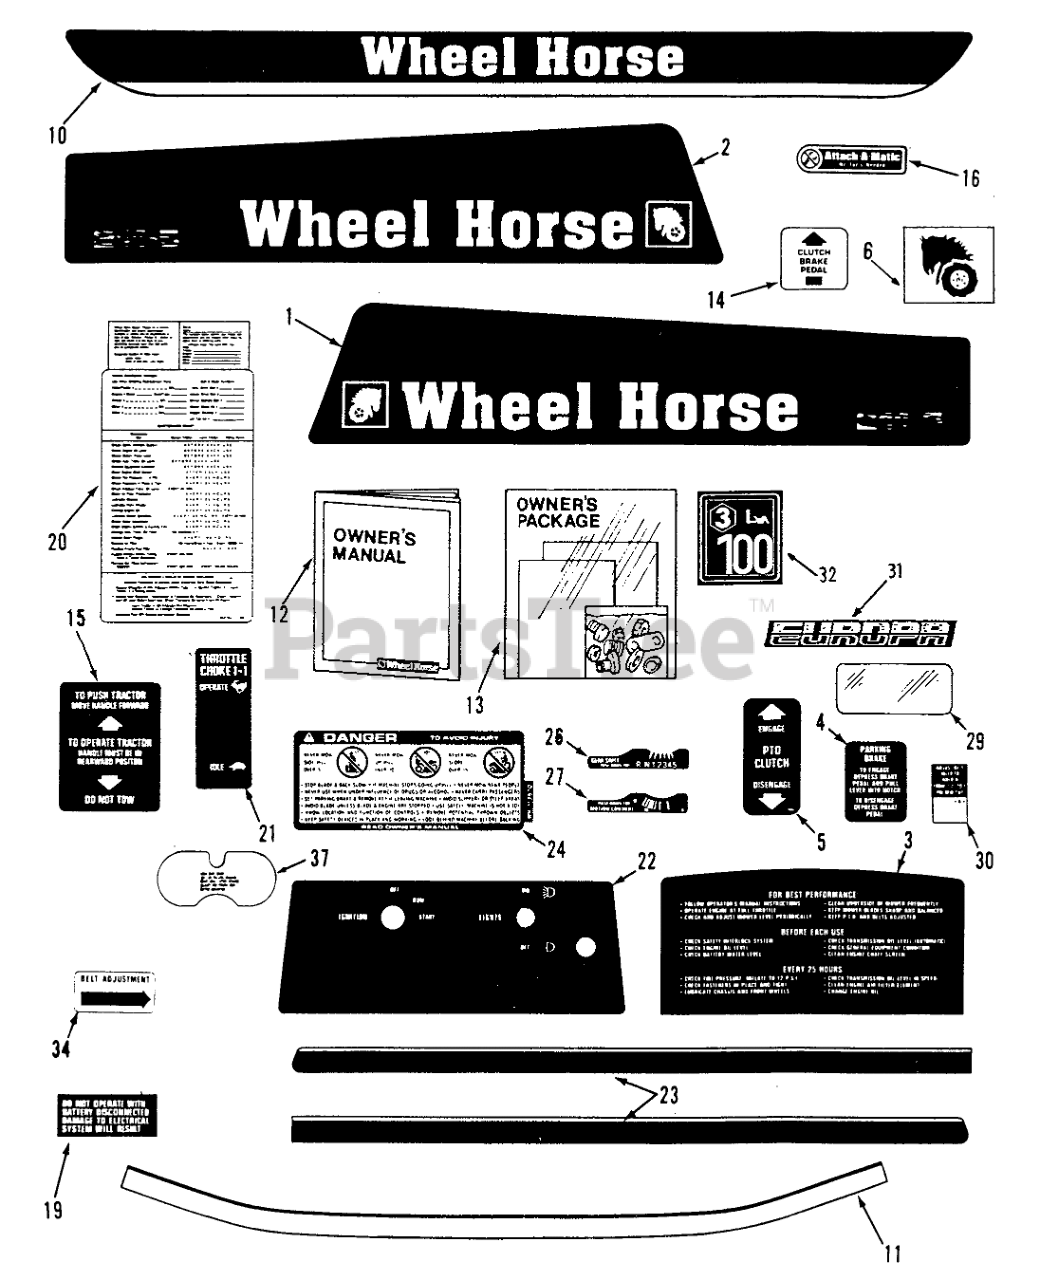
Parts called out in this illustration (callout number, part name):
1	DECAL-HOOD R.H.
2	DECAL-HOOD L.H.
3	DECAL-REAR HOOD
4	DECAL PARKING BRAKE
5	DECAL-PTO
6	DECAL-HORSE HEAD
10	DECAL-FENDER
11	DECAL FRONT HOOD
12	Owner-s Manuel-Tractor
13	New Tractor Loose Parts Package 212-5 SB
14	DECAL CLUTCH & BRAKE
15	DECAL-PUSH
16	Decal-Attach-A-Matic
19	DECAL ELECT SYSTEM
20	MAINTENANCE-DECAL
21	DECAL-THROTTLE
22	DECAL-BACK PLATE
23	DECAL HOOD STRIPE RH
24	DECAL-DANGER
26	DECAL-SHIFT 5-SPEED
27	DECAL-MOTION CONTROL
29	DECAL-OVERLAY
30	DECAL-PTO BELT ADJ
31	DECAL-EUROPA
32	DECAL-EUROPE
34	DECAL-BELT ADJUST
37	DECAL-SEAT LIFTER
